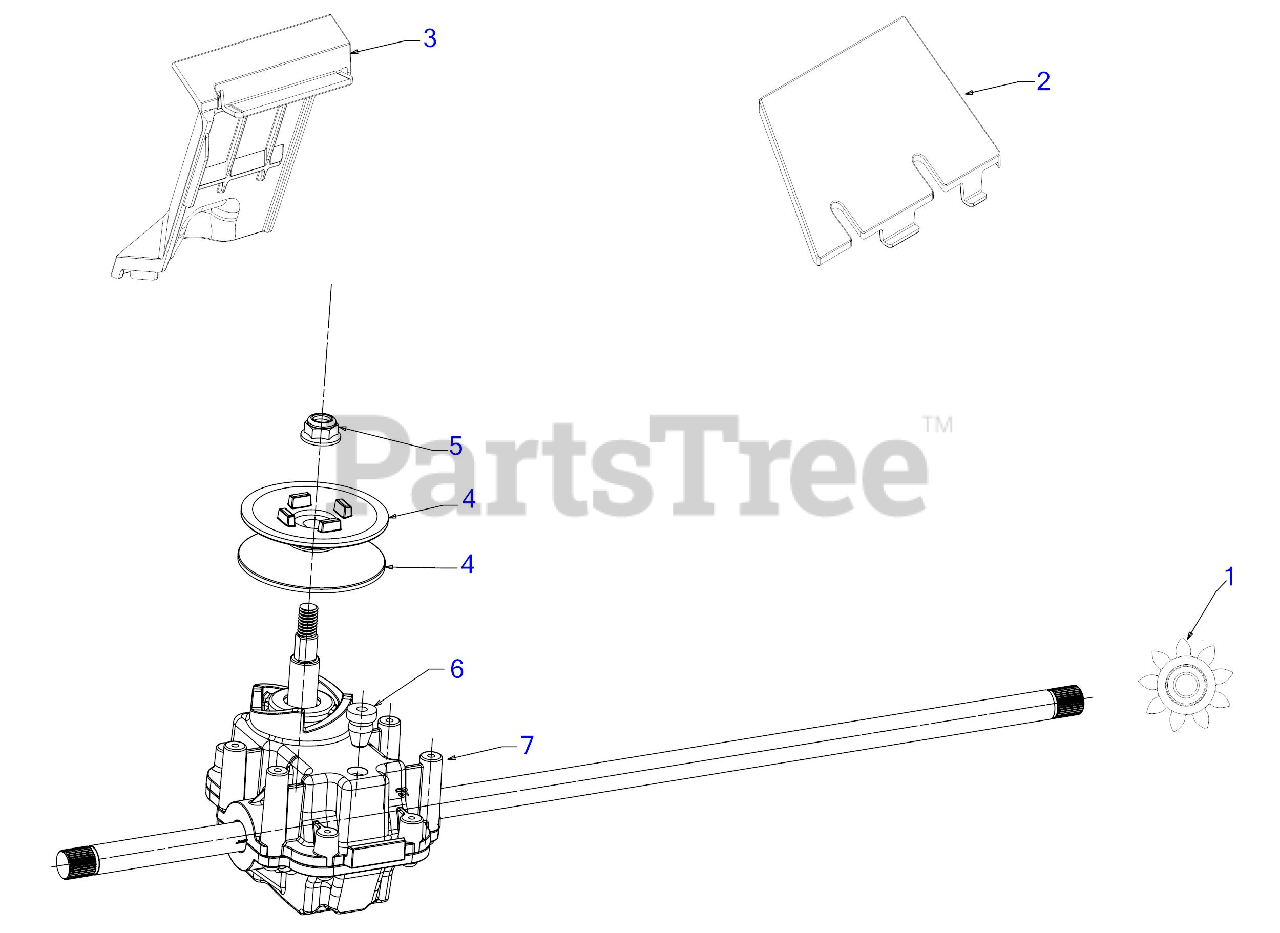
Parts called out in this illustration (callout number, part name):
1	SPUR GEAR 9T
2	TRANSMISSION COVER (REAR)
3	TRANSMISSION COVER (FRONT)
4	HALF PULLEY 2.50 OD
5	FLANGE LOCK NUT 5/16-18
6	RUBBER PLUG
7	TRANSMISSION ASSEMBLY
